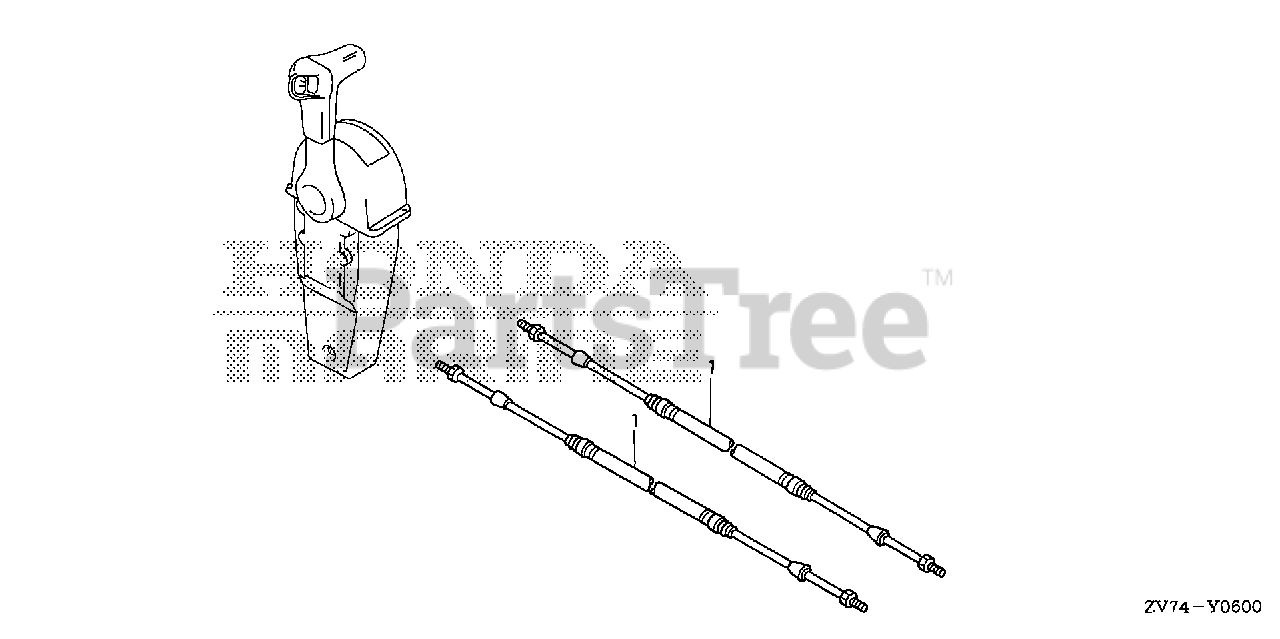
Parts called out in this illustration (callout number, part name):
1	CABLE ASSY., PUSH-PULL (33C-5FT)
1	CABLE ASSY., PUSH-PULL (33C-6FT)
1	CABLE ASSY., PUSH-PULL (33C-7FT)
1	CABLE ASSY., PUSH-PULL (33C-8FT)
1	CABLE ASSY., PUSH-PULL (33C-9FT)
1	CABLE ASSY., PUSH-PULL (33C-10FT)
1	CABLE ASSY., PUSH-PULL (33C-11FT)
1	CABLE ASSY., PUSH-PULL (33C-12FT)
1	CABLE ASSY., PUSH-PULL (33C-13FT)
1	CABLE ASSY., PUSH-PULL (33C-14FT)
1	CABLE ASSY., PUSH-PULL (33C-15FT)
1	CABLE ASSY., PUSH-PULL (33C-16FT)
1	CABLE ASSY., PUSH-PULL (33C-17FT)
1	CABLE ASSY., PUSH-PULL (33C-18FT)
1	CABLE ASSY., PUSH-PULL (33C-19FT)
1	CABLE ASSY., PUSH-PULL (33C-20FT)
1	CABLE ASSY., PUSH-PULL (33C-21FT)
1	CABLE ASSY., PUSH-PULL (33C-22FT)
1	CABLE ASSY., PUSH-PULL (33C-23FT)
1	CABLE ASSY., PUSH-PULL (33C-24FT)
1	CABLE ASSY., PUSH-PULL (33C-25FT)
1	CABLE ASSY., PUSH-PULL (33C-26FT)
1	CABLE ASSY., PUSH-PULL (33C-27FT)
1	CABLE ASSY., PUSH-PULL (33C-28FT)
1	CABLE ASSY., PUSH-PULL (33C-29FT)
1	CABLE ASSY., PUSH-PULL (33C-30FT)
1	CABLE ASSY., PUSH-PULL (33C-31FT)
1	CABLE ASSY., PUSH-PULL (33C-32FT)
